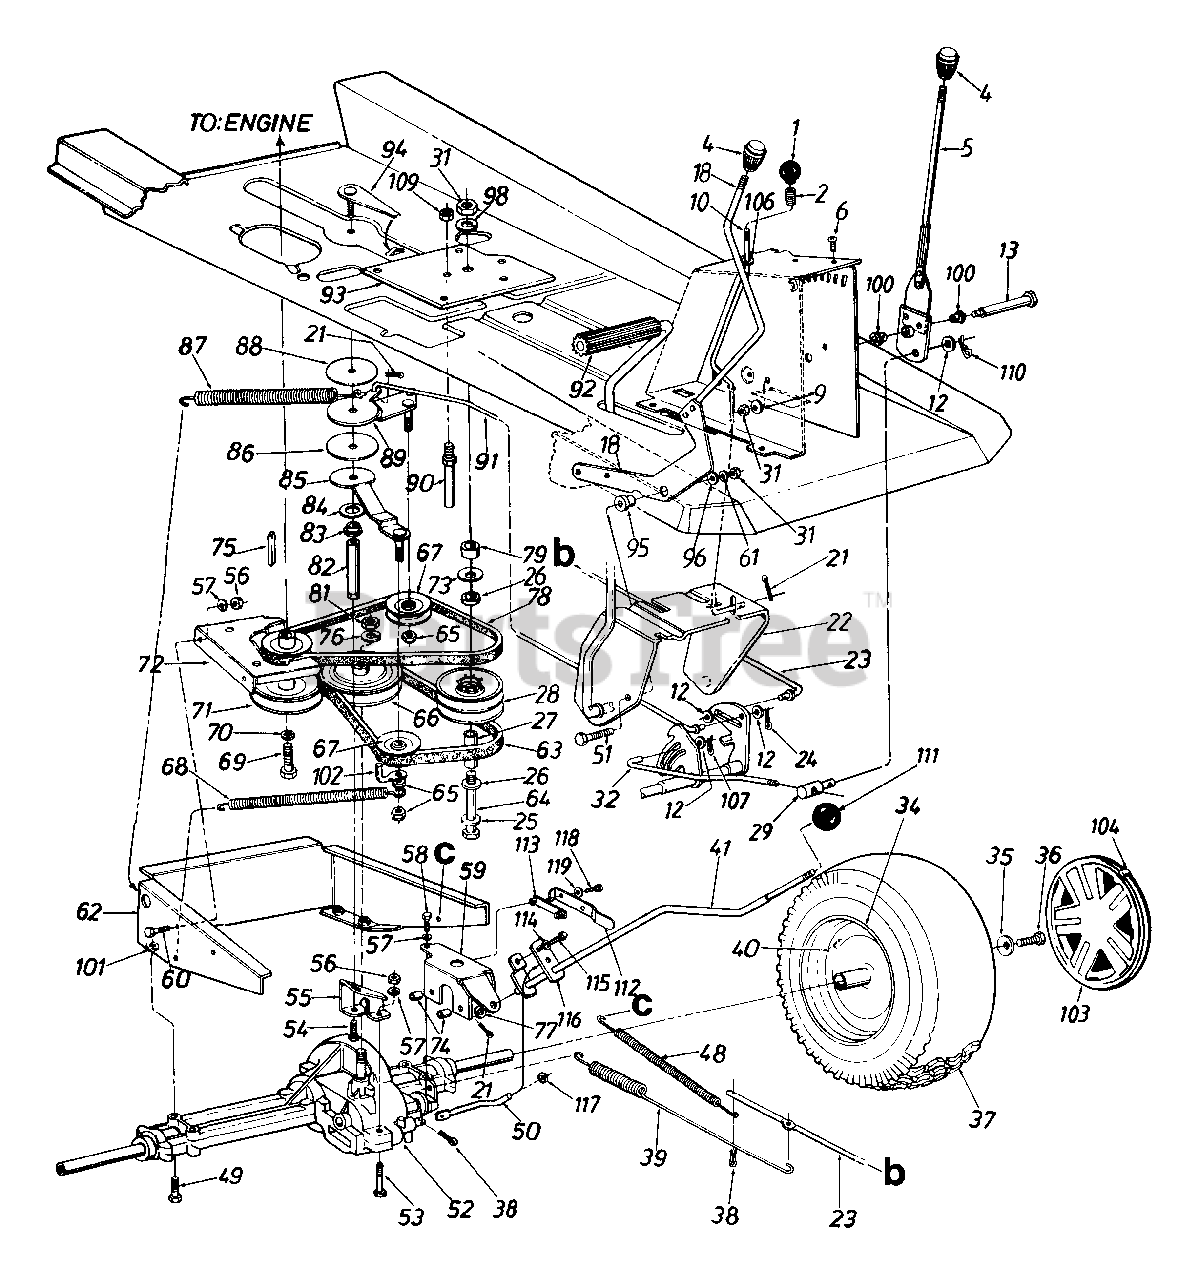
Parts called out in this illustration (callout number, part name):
1	Ball Knob 1/4-20 Thd.
2	Compression Spring
4	Shift Knob
5	Shifter Ass'y. w/Handle
6	Pan Hd. Tap Scr. #12 x .5" Lg.
9	Bell-Wash..4" I.D.
10	Parking Brake Rod
12	FI-Wash..34" I.D. x .68" O.D.
13	Shld. Bolt .498" Dia. x 4.75" Lg.
24	Cotter Pin 1/8" Dia. x 1.0"
25	FI-Wash..406" I.D. x 1.125"
26	Thrust Brg..56" I.D.
27	Spacer Sleeve 2.71" Lg.
28	Variable Speed Pulley Ass'y.
29	Ferrule
31	Hex Nut 3/8-16 Thd.
32	Speed Control Link
35	Bell-Wash..345" I.D. x.88"
36	Hex L-Bolt 5/16-24 x .75" Lg.
38	Cotter Pin 1/8" Dia. x 1.25"
39	Extension Spring 17" Lg.
40	Air Valve
41	Shift Lever Ass'y.
48	Extension Spring 8.25" Lg.
49	Hex Bolt 5/16-18 x 2.5" Lg.
50	Shift Rod
51	Hex Bolt 3/8-16 x 1.25" Lg.
52	Transaxle
53	Hex Bolt 1/4-20 x 1.75" Lg.
54	Hex Bolt 3/8-24 x .75" Lg.
57	L-Wash. 1/4" I.D.
58	Self-Tap Mach. Scr. 1/4-20 x 1.37" Lg.
59	Shift Lever Support Brkt.
60	Hex Bolt 1/4-20 x 1.0" Lg.
61	L-Wash. 3/8" I.D.
64	Hex Bolt 3/8-16 x 4.5" Lg.
65	Hex L-Nut 3/8-24 Thd.
66	"V"-Pulley
67	"V"-Belt Idler
68	Ext. Spring 6.37" Lg
69	Hex Bolt 7/16-20 x 1.0" Lg.
70	L-Wash 7/16" I D.
71	Engine Pulley
72	Upper Belt Guard
73	Bell-Wash 40" I. D, x 1.12" O.O.
74	Spacer 256" I.D. x .5" O.D.
75	Sq. Key 1/4" x 2.0" Lg.
76	Bell-Wash .567" I.D. x 1 125"
77	Fl-Wash. 469" I.D. x .88" 0 D.
78	"V"-Belt
79	Spacer 38" l D. x 1.0" O.D.
81	Hex Jam Nut 9/16-18 Thd
82	Torque Rod
83	Flange Bearing .378" I.D.
84	FI-Wash..64" I.D. x 1.24" 0 D.
85	Idler Bracket Ass'y.
86	Thrust Washer.635" I.D.
87	Extension Spring 7.58" Lg.
88	Thrust Wash. 385" I.D.
89	Idler Bracket Ass'y. For Clutch
90	Belt Guard Pin 3/8-16 x 2.75" Lg.
91	Clutch Rod
92	Foot Pad
96	FI-Wash..406" I.D. x 1.25" O.D.
98	L-Wash. 3/8" I.D. (Heavy Duty)
100	Flanged Nyliner Brg.
101	Hex Sems Nut 5/16-18 Thd.
102	Belt Guard
104	Spring Clip
106	Fl-Wash. 281" I.D. x .5" O.D.
107	Intern. Cotter Pin 1-1/8" Lg.
109	Hex Top L-Jam Nut 3/8-16 Thd.
110	Internal Cotter Pin 3/8" Dia.
111	Ball Knob
112	Spring Switch
113	Insulator Nut Plate
114	Bell-Wash..265" I.D. x .75" O.D.
115	Hex Bolt 1/4-20 x .5" Lg.
116	Shift Lever Adjusting Link
117	Retaining Ring
118	Hex Wash. Hd Scr. #8 x .5" Lg.
119	Plastic Washer
